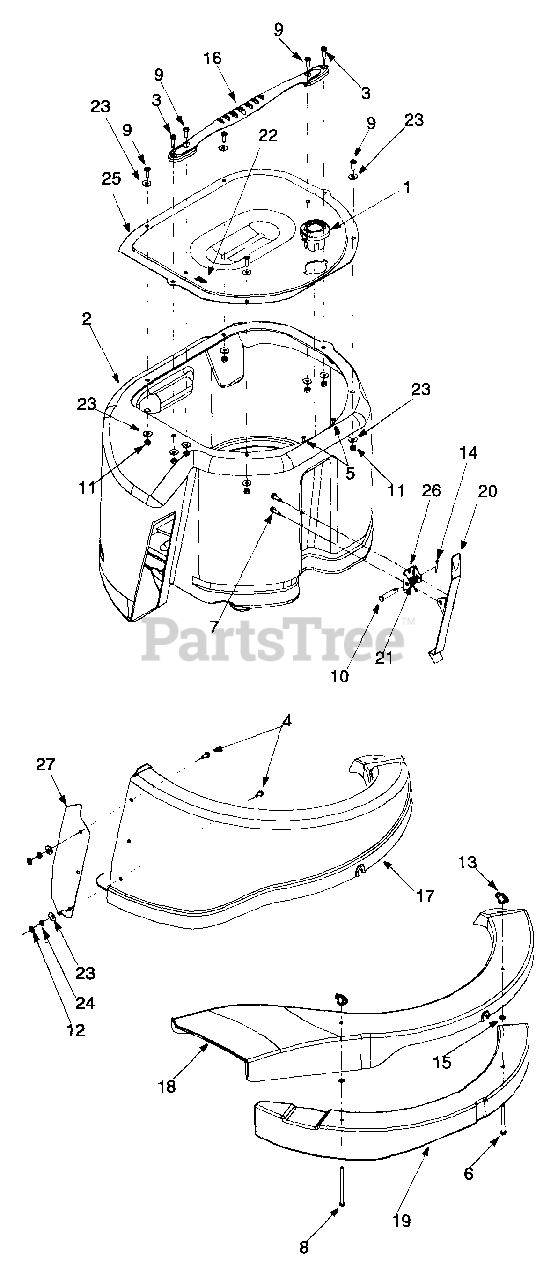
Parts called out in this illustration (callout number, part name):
1	Flow Indicator Assembly
2	Grass Bag Assembly
3	Machine Screw 1/4-20 x 1.0
4	Machine Screw 1/4-20 x 0.5"
5	Hex Screw #10-16 x 0.5"
6	Hex Screw 1/4-20 x 2.75"
7	Self-Tapping Screw 1/4-20 x 0.75"
8	Hex Screw 1/4-20 x 3.75"
9	Machine Screw 1/4-20 x 0.75"
10	Clevis Pin
11	Hex Sems Nut 1/4-20
12	Jam Nut
13	Wing Nut
14	Cotter Pin
15	Speed Nut
16	Bag Handle
17	Discharge Chute: Grass Bag
18	Side-Discharge Chute
19	Mulching Plug
20	Bag Release Lever
21	Torsion Spring
22	Clip Spring
23	Flat Washer
24	Lock Washer
